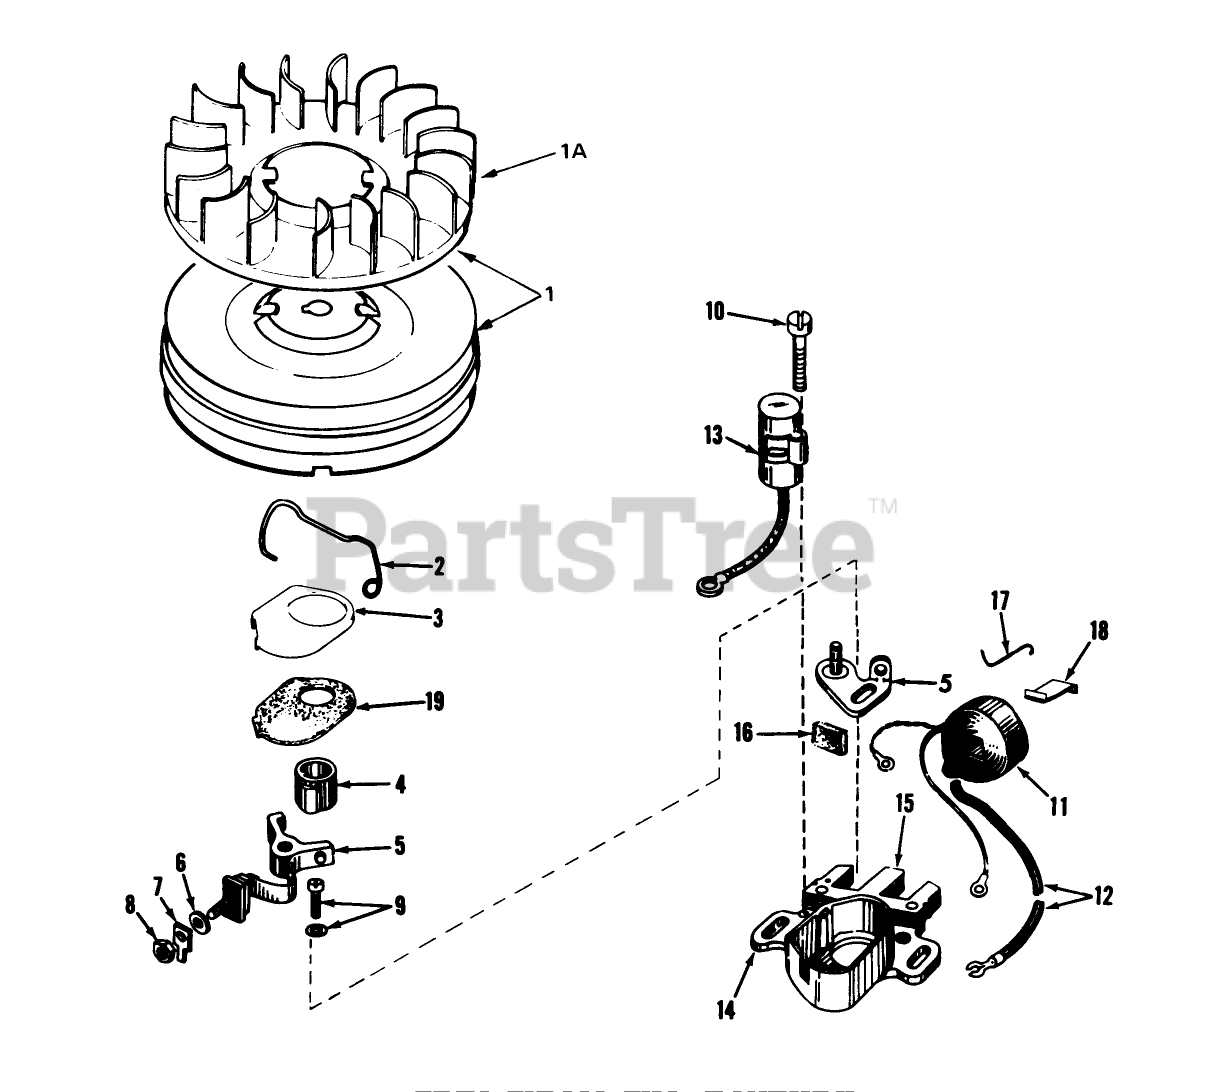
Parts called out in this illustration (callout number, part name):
1	Flywheel (Incl. No. 1A)
2	Spring Breaker Box
3	Cover-Dust
4	Cam-Breaker
5	Breaker Assy.
6	Washer
7	Terminal, Ground
8	DECAL
9	Breaker Screw
10	Condenser Screw
11	Coil Assy. (Incl. No. 12)
12	Wire, Lead
13	Condenser
14	Core Plate
15	Stator Assy. (Incl. Ref. #2 thru 11, 13, 14, 16, 17 19)
16	Felt,Cam Wiper
17	Clip, Coil
18	Spring Coil Wedge
19	Gasket-Dust Cover
19	Gasket, Dust Cover
